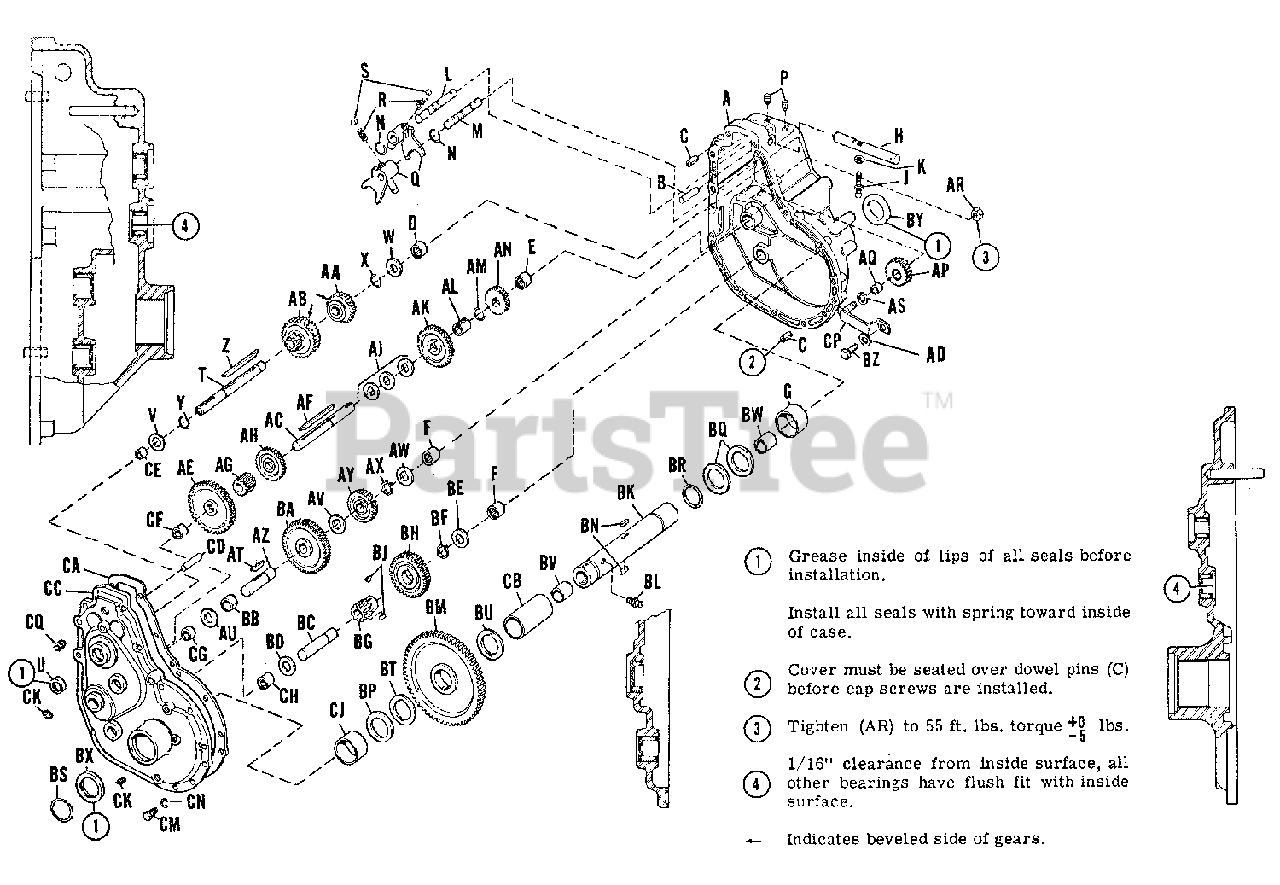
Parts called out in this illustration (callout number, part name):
A	CASE, Gear, Complete w/Bearings & Dowel Pins
B	PIN, Roll
C	PIN, Roll
D	BEARING, Needle
E	BEARING, Needle
F	BEARING, Needle
G	BEARING, Axle Tube
H	ROD, Shift
J	STEM, Shift
K	NUT, Hex, Full, 3/8"-24 NF
L	SHAFT, Shifter, Rev. Med.
M	SHAFT, Shifter, High, Low
N	RING, Retaining
P	SETSCREW, Hollow Head, Cone Point, 5/16"-18 NC x 1/2" LG
Q	FORK, Shift
S	BALL, Shift Lock
T	SHAFT, Pulley
X	RING, Retaining
Y	RING, Retaining
AA	PINION ASSEMBLY, Rev., II
AB	PINION ASSEMBLY, Rev., I & III
AC	SHAFT, 1st Intermediate
AD	WASHER, Lock, 3/8" Internal Shakeproof
AE	GEAR, Driven, I
AG	PINION, 1st Intermediate
AH	PINION, Driven, III
AJ	SPACER, Transmission Gear
AK	GEAR, Driven, II
AM	RING, Retaining
AN	PINION, Reverse
AP	GEAR, Reverse
AQ	SPACER, Reverse Gear
AR	NUT, Lock, 1/2"-20 NF
AX	RING, Retaining
AY	PINION, 2nd Intermediate
AZ	SHAFT, 2nd. Intermediate
BA	GEAR, 2nd Intermediate
BC	SHAFT, 3rd Intermediate
BF	RING, Retaining
BG	PINION, 3rd Intermediate
BH	GEAR, 3rd Intermediate
BJ	KEY, Woodruff
BK	TUBE, Axle
BL	FITTING, Grease
BM	GEAR, Drive
BT	WASHER, Axle Tube
BU	WASHER, Axle Tube
BZ	CAPSCREW, Hex, 3/8"-16 x 5/8" LG
CA	GASKET, Gear Case
CB	SPACER, Axle Tube
CC	COVER, Gear Case, Complete w/bearings
CD	PIN, Roll
CE	BEARING, Needle
CF	BEARING, Needle
CG	BEARING, Needle
CH	BEARING, Needle
CJ	BEARING, Axle Tube
CK	PLUG, Pipe, 3/8"
CM	CAPSCREW, Hex, 5/16"-18 NC x 1" LG
CN	WASHER, Lock, 5/16"
CP	PIN ASSEMBLY, Rev. Gear
CQ	PLUG, Pipe, 3/8"
